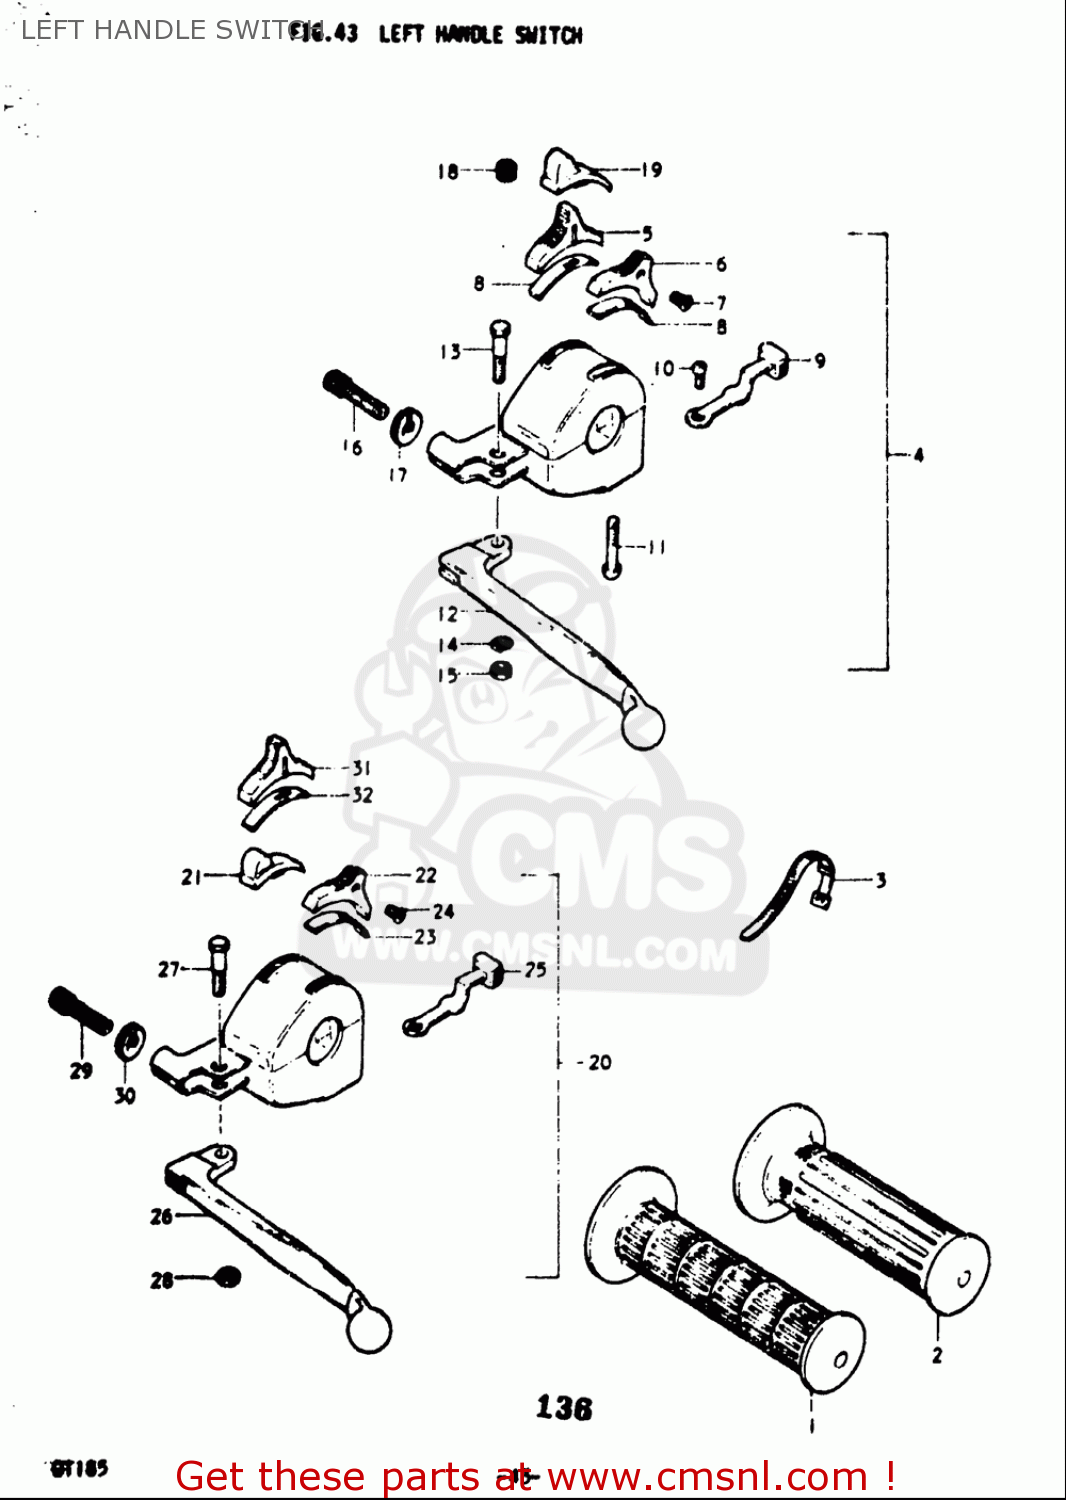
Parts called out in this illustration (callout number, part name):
1	GRIP,L
2	GRIP,L
3	CLAMP(L:120)
5	KNOB,HANDLE SWITCH
6	KNOB
7	SCREW
8	PLATE,SWITCH KNOB
10	SCREW
11	SCREW
12	LEVER,CLUTCH
13	BOLT
14	WASHER,LOCK
15	NUT
16	ADJUSTER,CABLE
17	NUT,CABLE ADJUSTER
22	KNOB
23	PLATE,SWITCH KNOB
24	SCREW
26	LEVER,CLUTCH
27	BOLT
28	NUT
29	ADJUSTER,CABLE
30	NUT,CABLE ADJUSTER
31	KNOB,HANDLE SWITCH
32	PLATE,SWITCH KNOB
